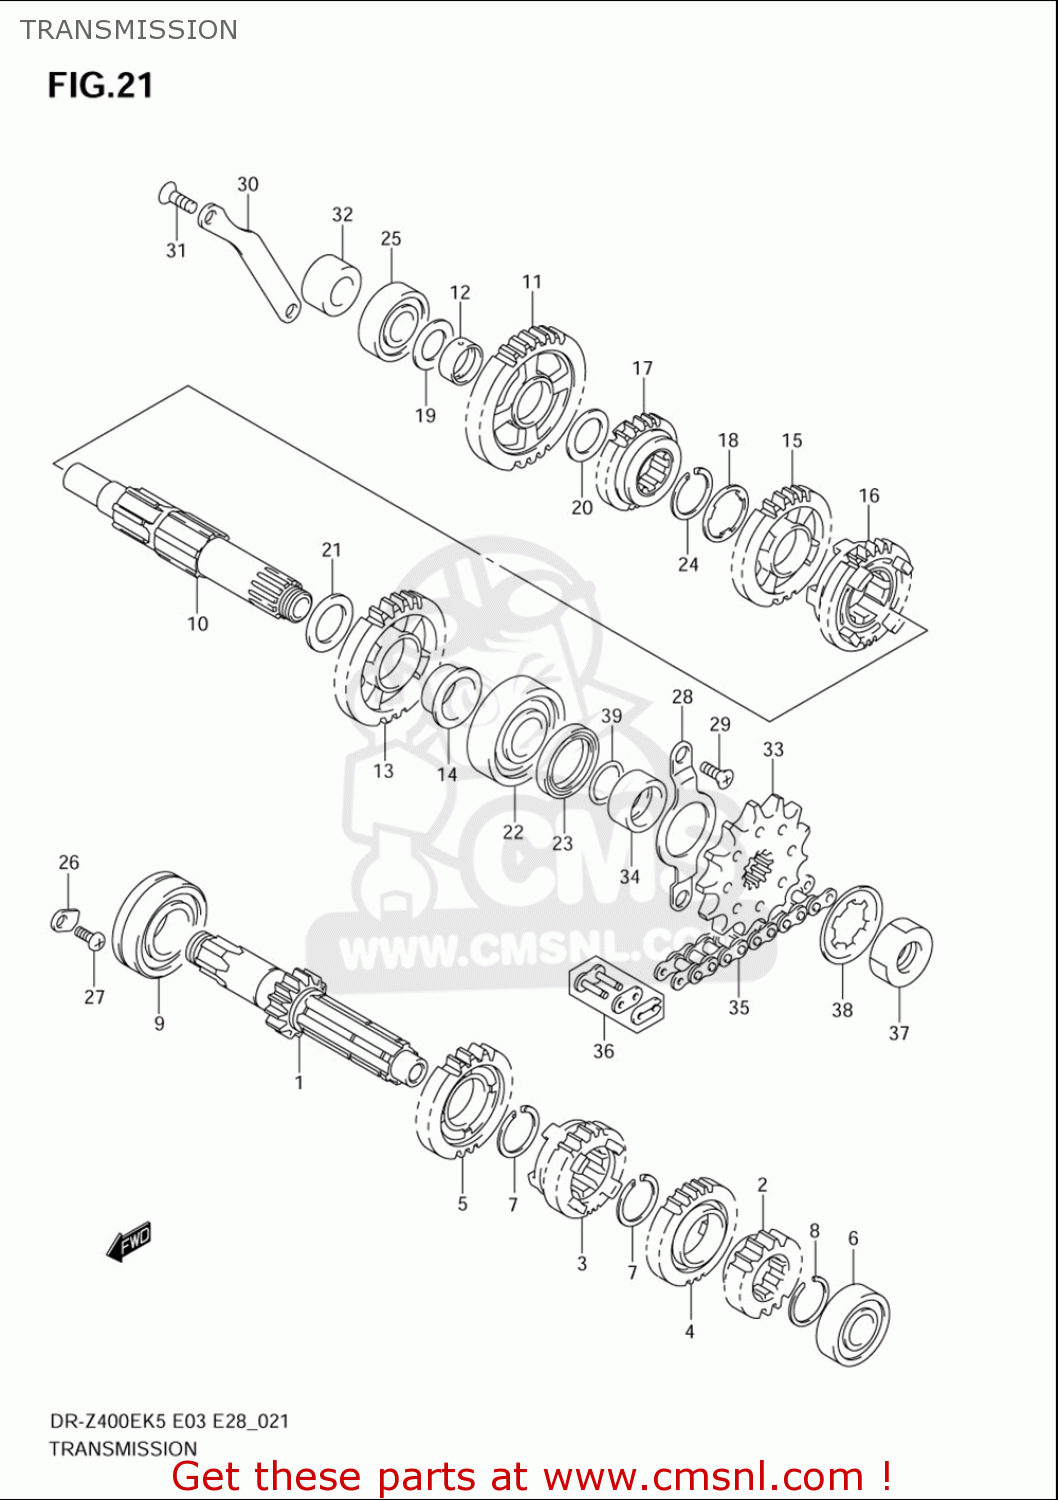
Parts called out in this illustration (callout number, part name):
1	SHAFT,COUNTER(NT:14)
2	GEAR,2ND DRIVE(NT:15)
3	GEAR,3RD DRIVE(NT:16)
4	GEAR,4TH DRIVE(NT:22)
5	GEAR,5TH DRIVE(NT:22)
6	BEARING(17X40X12)
7	CIRCLIP
8	CIRCLIP
9	BEARING(25X52X15)
10	SHAFT,DRIVE
11	GEAR,1ST DRIVEN(NT:32)
12	BUSH,1ST DRIVEN GEAR
13	GEAR,2ND DRIVEN(NT:26)
14	BUSH,2ND DRIVEN GEAR
15	GEAR,3RD DRIVEN(NT:22)
16	GEAR,4TH DRIVEN(NT:24)
17	GEAR,5TH DRIVEN(NT:19)
18	WASHER,LOCK
19	SHIM(17X30X1)
20	SHIM(20X30X1)
21	SHIM(22X34X1)
22	BEARING(22X56X16)
23	SEAL,OIL(30X40X6)
24	CIRCLIP
25	BEARING(17X40X12)
26	RETAINER
27	BOLT(6X12)
28	RETAINER,DRIVE SHAFT OIL SEAL
29	SCREW(6X14)
30	RETAINER,KICK IDLE GEAR
31	SCREW
32	SPACER(17X30.5X16.3)
33	SPROCKET,ENGINE(NT:14)
34	SPACER,ENGINE SPROCKET
35	CHAIN ASSEMBLY,DRIVE RK520
36	JOINT SET,CHAIN
37	NUT
38	WASHER,LOCK
39	O RING(D:2.5,ID:21)
